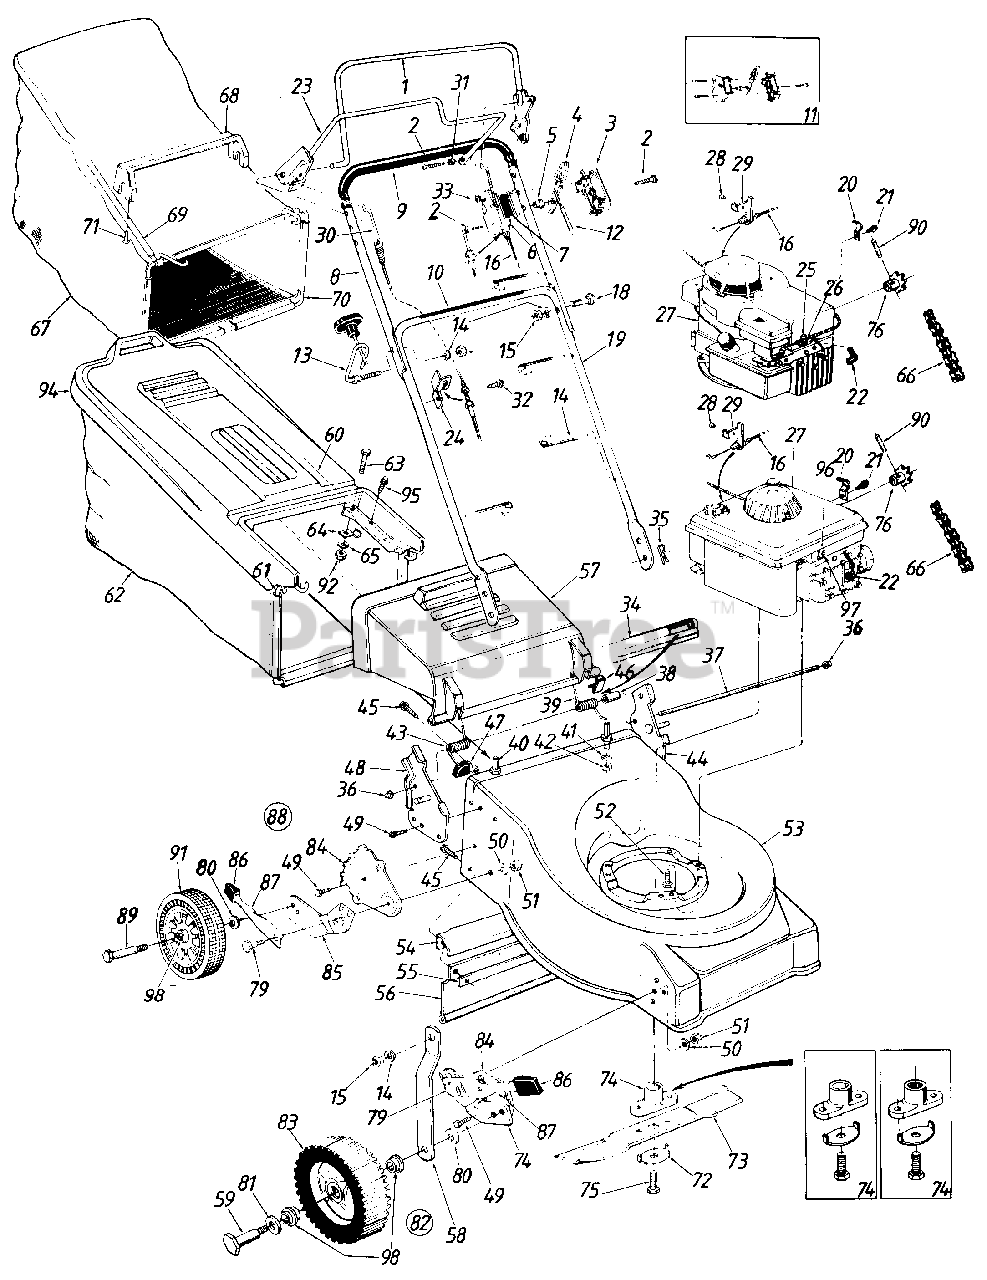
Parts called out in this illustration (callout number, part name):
1	Control Handle Ass'y.
2	Truss Mach. B-Tap Scr. #12 x 1.5" Lg.
3	Control Panel Half
4	Throttle Control Lever
5	Control Disc Pin
6	Clutch Panel Half
7	Control Label-Throttle
8	Upper Handle
10	Instruction Label-Handle
11	Control Housing Comp.
12	Throttle Wire-58" Lg.
13	Rope Guide Bolt
14	L-Wash. 5/16" I.D.*
15	Hex Nut 5/16-18 Thd.*
16	Control Cable-43" Lg.
18	Curved Carriage Bolt 5/16-18 x 1.38" Lg.
19	Lower Handle
20	Cable Clamp
21	Hex B-Tap Scr. #10 x .38" Lg.
22	Spark Plug Boot
23	S.P. Bail Ass'y.
24	Cable Mounting Brkt.
25	Cable Clamp
26	Hex AB-Tap Scr. #8 x .5" Lg.
27	Engine
28	Pop Rivet .156" Dia.
29	Cable Bracket
30	Drive Cable-47" Lg.
31	Spacer.23" I.D.
32	Hex Wash. AB-Tap Scr. 5/16" x.75" Lg.
33	Spr. Wash. .206" I.D.
34	Seal-Extrusion
35	Int. Cotter Pin 5/16" Dia.
36	Cap Speed Nut
37	Hinge Pin 17.75" Lg.
38	Spacer.255" I.D.
39	Torsion Spring-L.H.
40	Shld. Pin 3/8-24 x 1.43" Lg.
41	L-Wash. 3/8" I.D.*
42	Hex Jam Nut 3/8-24 Thd.
43	Torsion Spring-R.H.
44	Handle Brkt. Ass'y.-L.H.
45	Torx Mach. AB-Tap Scr. 1/4 x .62" Lg.
46	Deflector Plug
47	Corner Plug
48	Handle Brkt. Ass'y.-R.H.
49	Hex L-Wash. AB-Tap Scr. 1/4 x.62" Lg.
50	Bell-Wash. .39" I.D. x 1.38" O.D.
51	Hex Nut 3/8-16 Thd.*
52	Hex L-Wash. Hd. Scr. 3/8-16x 1" Lg.
57	Rear Chute Deflector
58	Link 5.06" Lg.
59	Front Axle Bolt
60	Rear Catcher Frame
61	Front Catcher Frame
62	Grass Bag
63	Truss Mach. Scr. 1/4-20 x 1" Lg.
64	Hardtop Mtg. Clamp
65	Fl-Wash..281" I.D.
66	#48 Chain 1/2" Pitch 50 Links (Endless)
67	Grass Bag
68	Bag Handle
69	Rear Catcher Frame
70	Front Catcher Frame
71	Hex AB-Tap Scr. #12 x 1.25"
72	Blade Bell-Wash. .44" I.D. x 2.38"
73	21" Blade
74	Blade Adapter Kit Keyed
75	Hex Bolt 3/8-24 x 1.5" Lg.
76	10 Tooth Sprocket Ass'y.
79	Shld. Bolt .50" Dia. x .357"
80	Bell-Wash. .38" I.D. x .88n O.D.
81	Fl-Wash. .531 " 1.D.
82	Front Height Adj. Ass'y. Comp.-R.H.
83	Front Wheel Ass'y. Comp.
84	Index Plate
85	Pivot Bar
86	Spring Lever Knob
87	Spring Lever
88	Rear Height Adj. Ass'y. Comp.-R.H.
89	Rear Axle Bolt
90	Spring Pin 3/16" Dia.
91	Rear Wheel Ass'y. Comp.
92	Hex Nut 1/4-20 Thd.
94	Hardtop Bag Cover
95	Hex AB-Tap Scr. 1/4 x .62" Lg.
96	Cable Clamp
97	Hex B-Tap Scr. #10 x .62" Lg.
98	Flanged Brg. .50" I.D.
